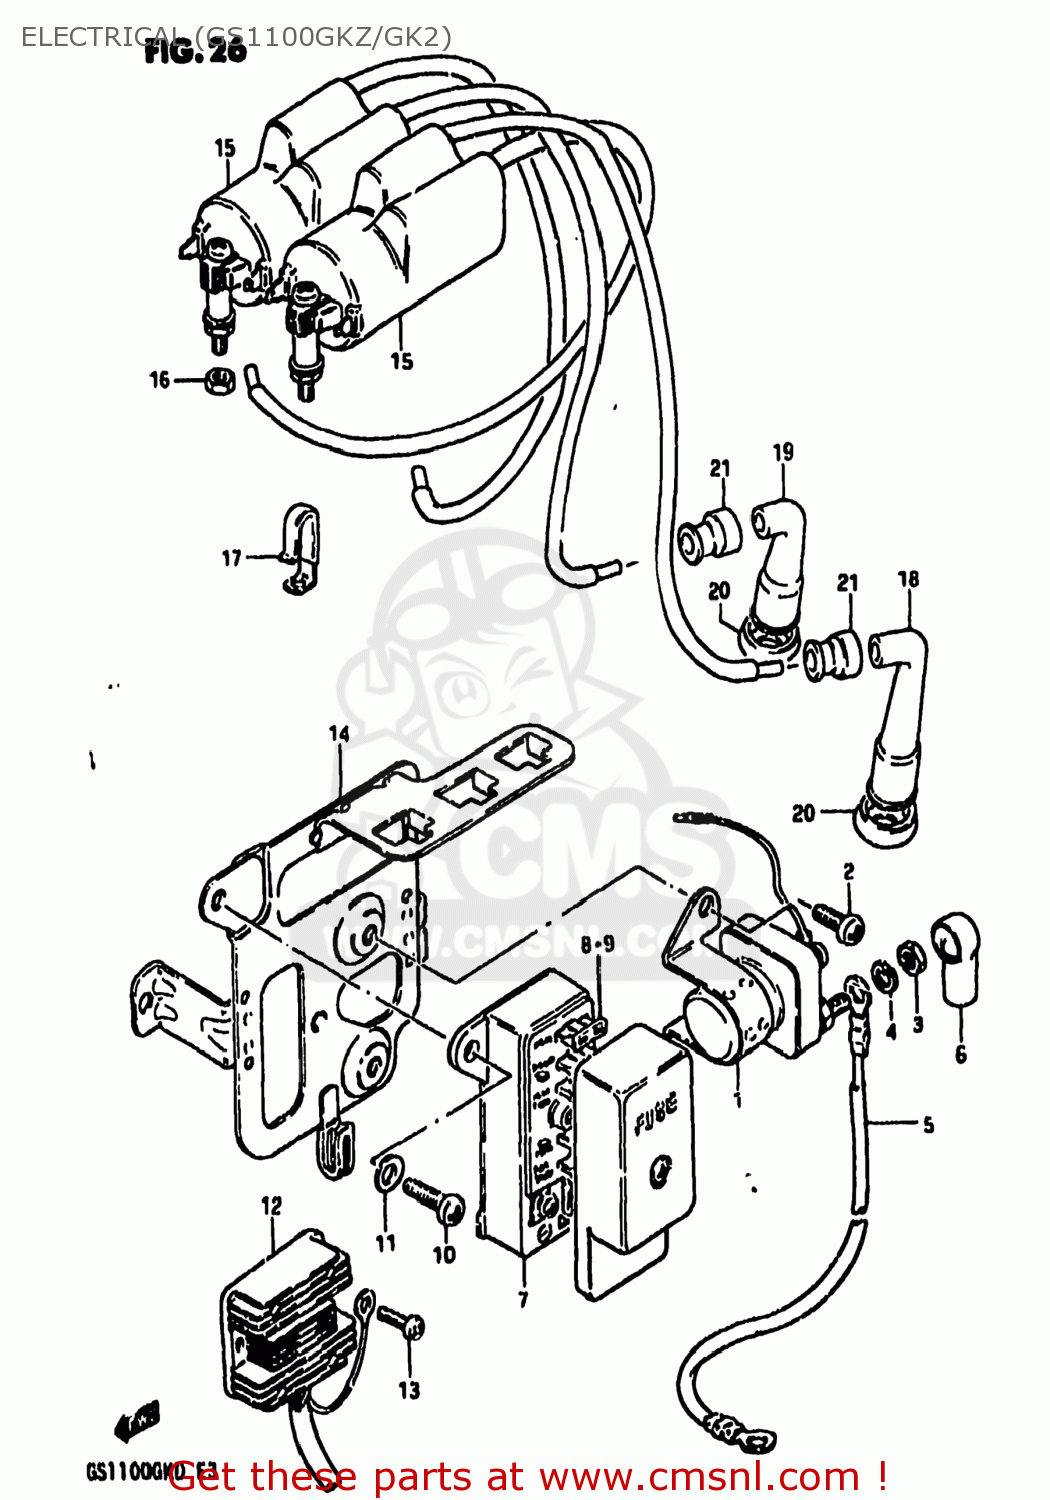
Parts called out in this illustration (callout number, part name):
1	RELAY ASSY,STARTING MOTOR
2	SCREW
3	NUT 6MM
4	LOCK WASHER
5	CABLE,STARTING MOTOR
6	CAP,STARTER RELAY
7	BOX ASSEMBLY,FUSE
8	FUSE(10A)
9	FUSE(15A)
10	SCREW 6X12
11	WASHER
12	RECTIFIER ASSEMBLY
13	SCREW 6X12
14	HOLDER COMP,ELECTRONIC PARTS
15	COIL ASSEMBLY,IGNITION
16	NUT
17	CLAMP
18	CAP ASSY,SPARK PLUG
19	CAP,SPARK PLUG
20	SEAL,SPARK PLUG
21	SEAL,SPARK PLU
